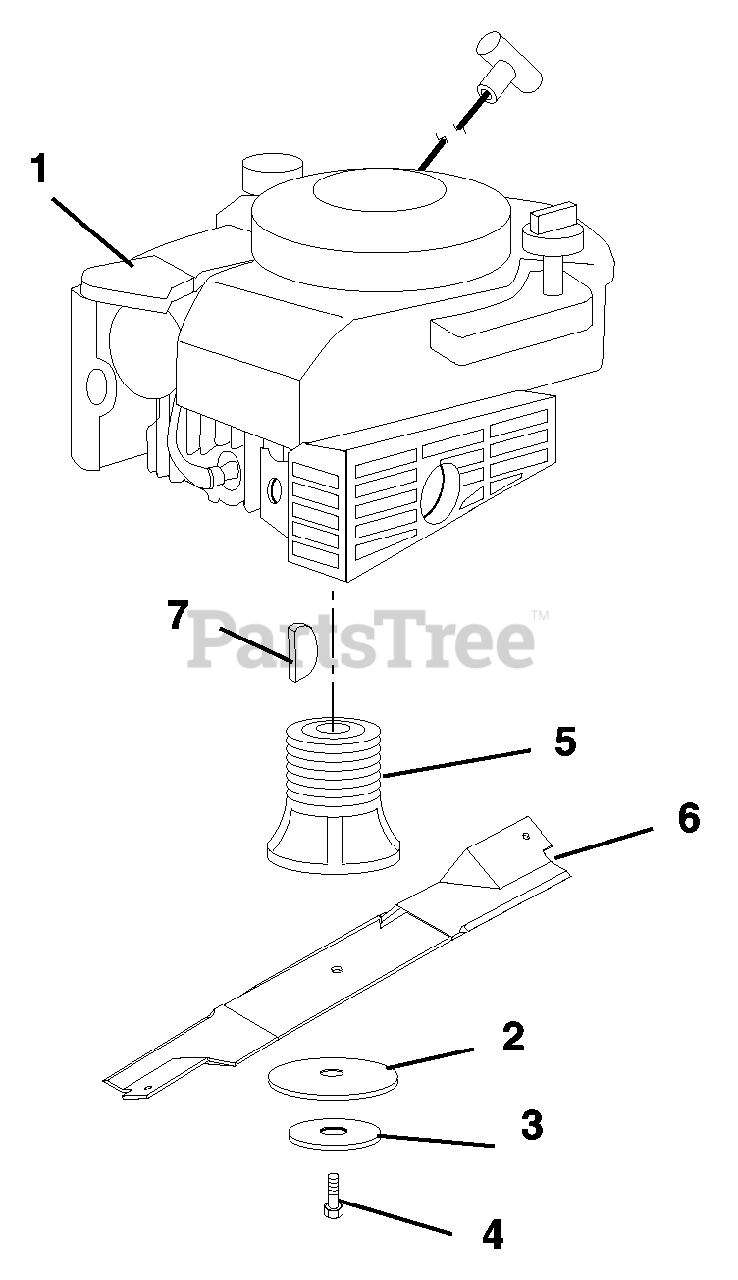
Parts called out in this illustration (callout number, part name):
1	ENGINE, B&S 6.0HP QUANTUM XM
2	WASHER, CUPPED
3	WASHER M10 11X30X2.5
4	BLT-HEX .375-24 X 2.00 UNF
5	HUB, SELF PROPELLED
7	KEY-WDRF .156X.625X.25 SAE 6
